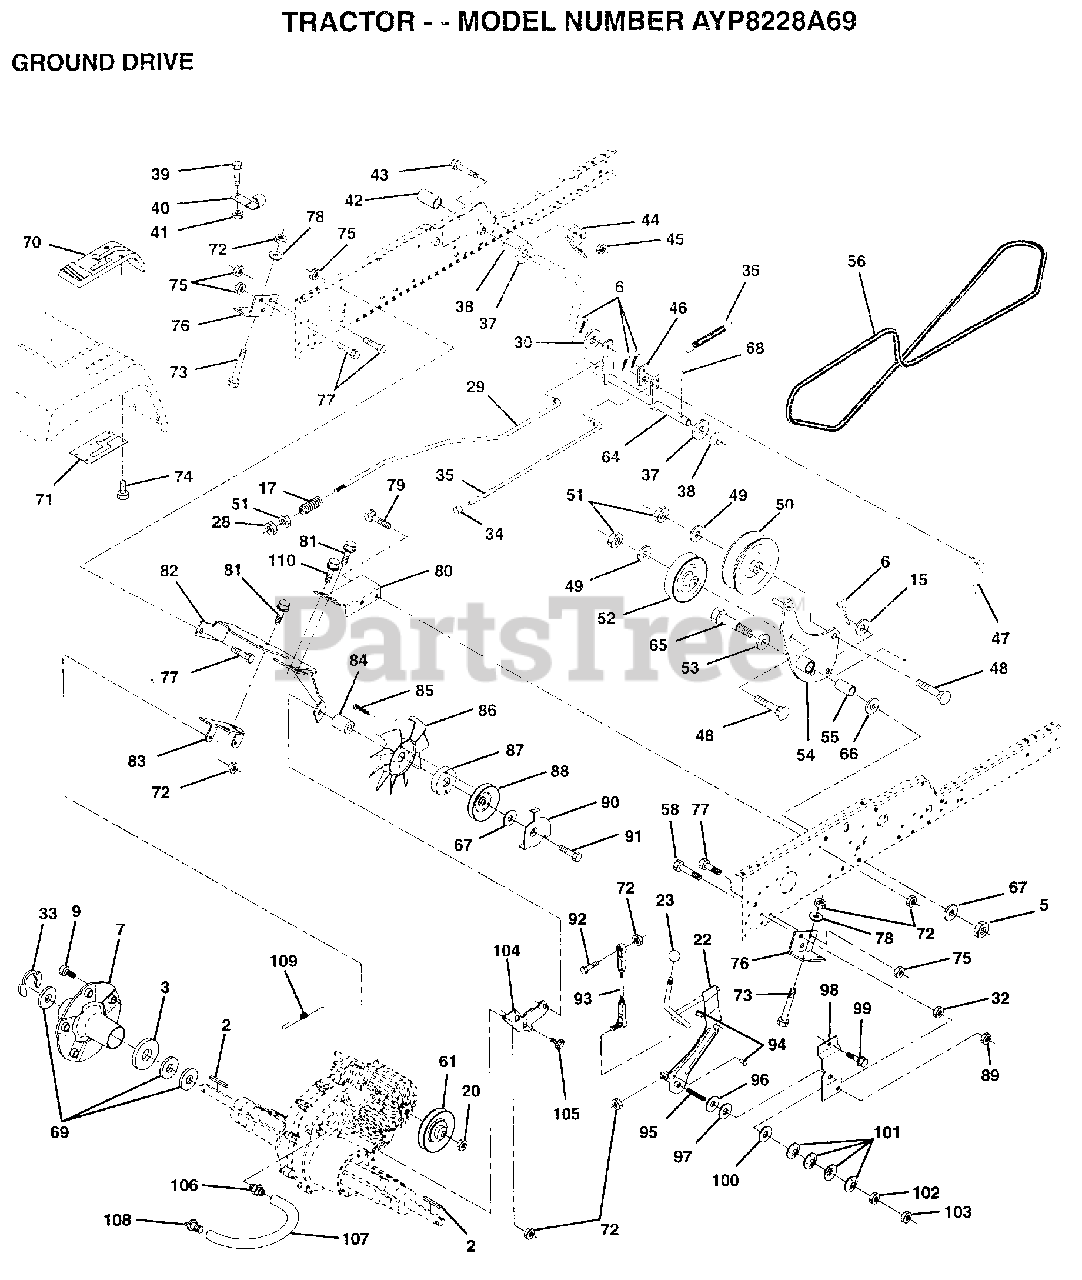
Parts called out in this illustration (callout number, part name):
2	KEY 1/4 X 2.5
6	COTTER PIN
7	HUB WHEEL ASM
9	BOLT.HUB.WHL.REAR
15	WASHER
17	SPRING ROD BRAKE
22	SHAFT ARM ASM
23	WASHER T
23	KNOB.DUCKHEAD.1/2
28	NUT
29	ROD BRAKE
30	WASHER HYT
32	NUT
33	E RING HYT
35	ROD BRAKE PART GT
36	SPRING.GRND.DRIVE
37	WASHER
38	BUSHING.NYLINER
39	SCREW
40	ACT-SWITCH T
42	PEDAL COVER T
43	BOLT LT
44	BRKT SWITCH GT
45	NUT
46	RETAINER.SPRING
47	ROD.CLUTCH
48	BOLT.3/8-16X1.50
49	WASHER
50	FLAT IDLER PULLEY
52	PULLEY.IDLER.V.GR
53	WASHER T
54	ARM.ASM.IDLER.CLU
55	"LY, BEARING"
56	BELT-V 84.5
58	BOLT
61	PULLEY TRANSAXLE
65	AXLE BOLT
66	WASHER.HARD.BLADE
67	WASHER
68	ROLL PIN STD
69	WASHER
71	PLATE CONSOLE S
73	BOLT FIN HEX 5/16
74	SCREW HEXWSH H-L
75	NUT.7/16
76	BRACKET TRAN VGTH
77	BOLT
78	WASHER
79	BOLT
80	BRACKET TORQUE RH
81	SCREW
83	STRAP TORQUE MID
84	SPACER
85	SCREW YTV
86	"FAN 7"" HYDRO"
87	ADAPTER FAN
89	NUT GTV
90	KEEPER BELT
91	SCREW.HXWSH.3/8
93	LINK ASM SHIFT
94	XMAS TREE FASTNER
95	SCREW SET 5/16
96	WASHER NICKEL PLT
97	BEARING THRUST
98	BRACKET SHIFT
99	SCREW LT
100	WASHER COMPRESSIN
101	WASHER
102	NUT HEX NYLOCK
103	JAM NUT TI
104	BRACKET IDLER
105	SCREW CRT
109	SPRING BRAKE
110	HINGE SCREW
